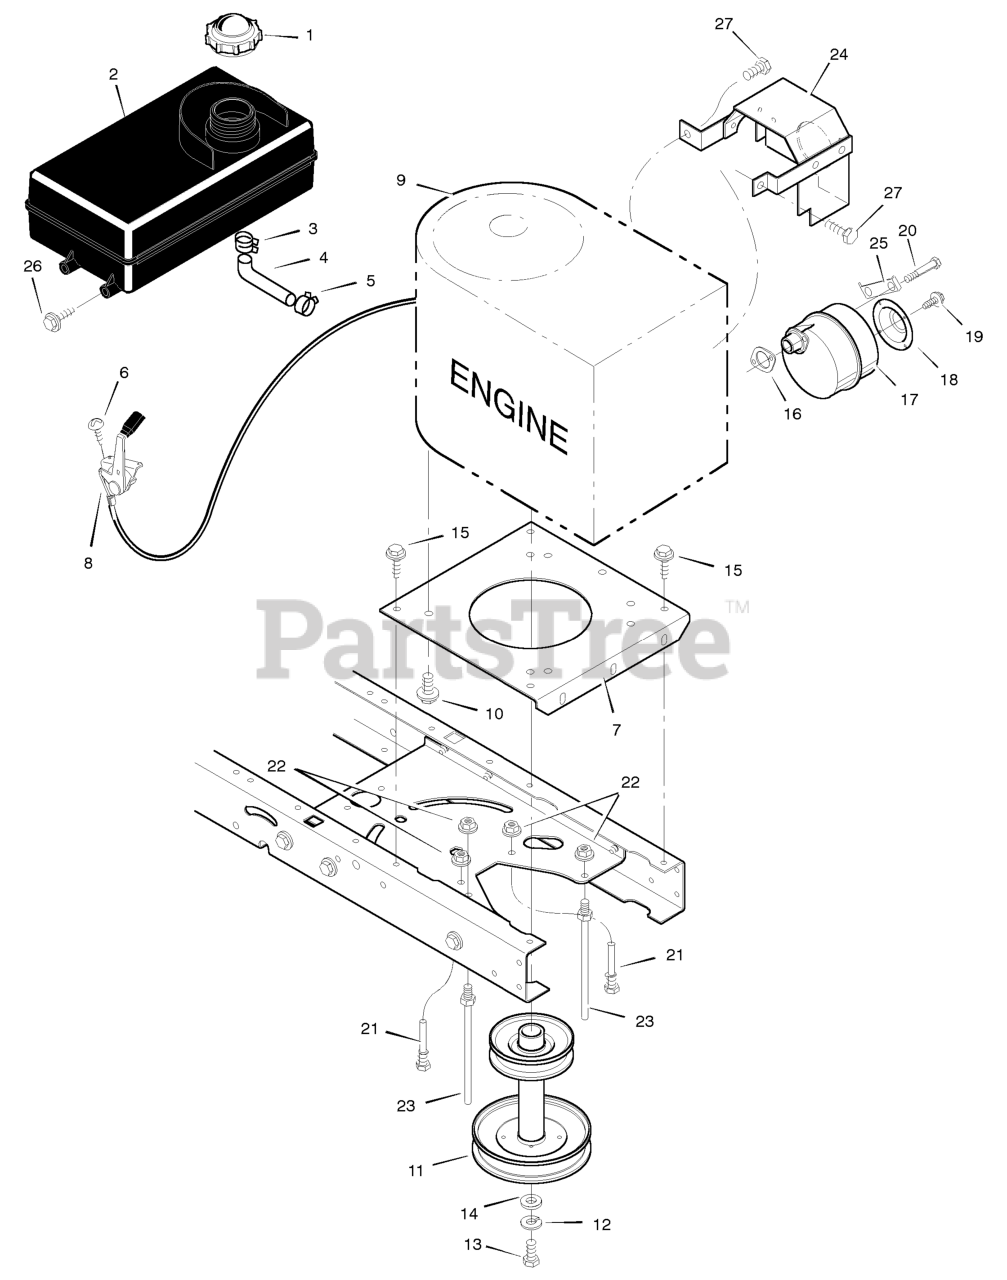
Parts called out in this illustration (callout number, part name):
1	Fuel Cap
2	TANK, Fuel 1.4 Gal.
3	Hose Clamp
4	Fuel Line
5	Hose Clamp
7	Plate, Engine
8	Throttle Control
9	Engine *
10	Bolt, Engine Mount
11	Stack Pulley Assembly
12	Lockwasher
13	Bolt, Hex
16	GASKET, Exhaust
17	Muffler
18	Deflector, Muffler
20	Bolt, Hex
21	Guide, Belt
22	Nut, Flange
23	Guide, Belt
24	Shield, Heat
25	Lock, Screw
